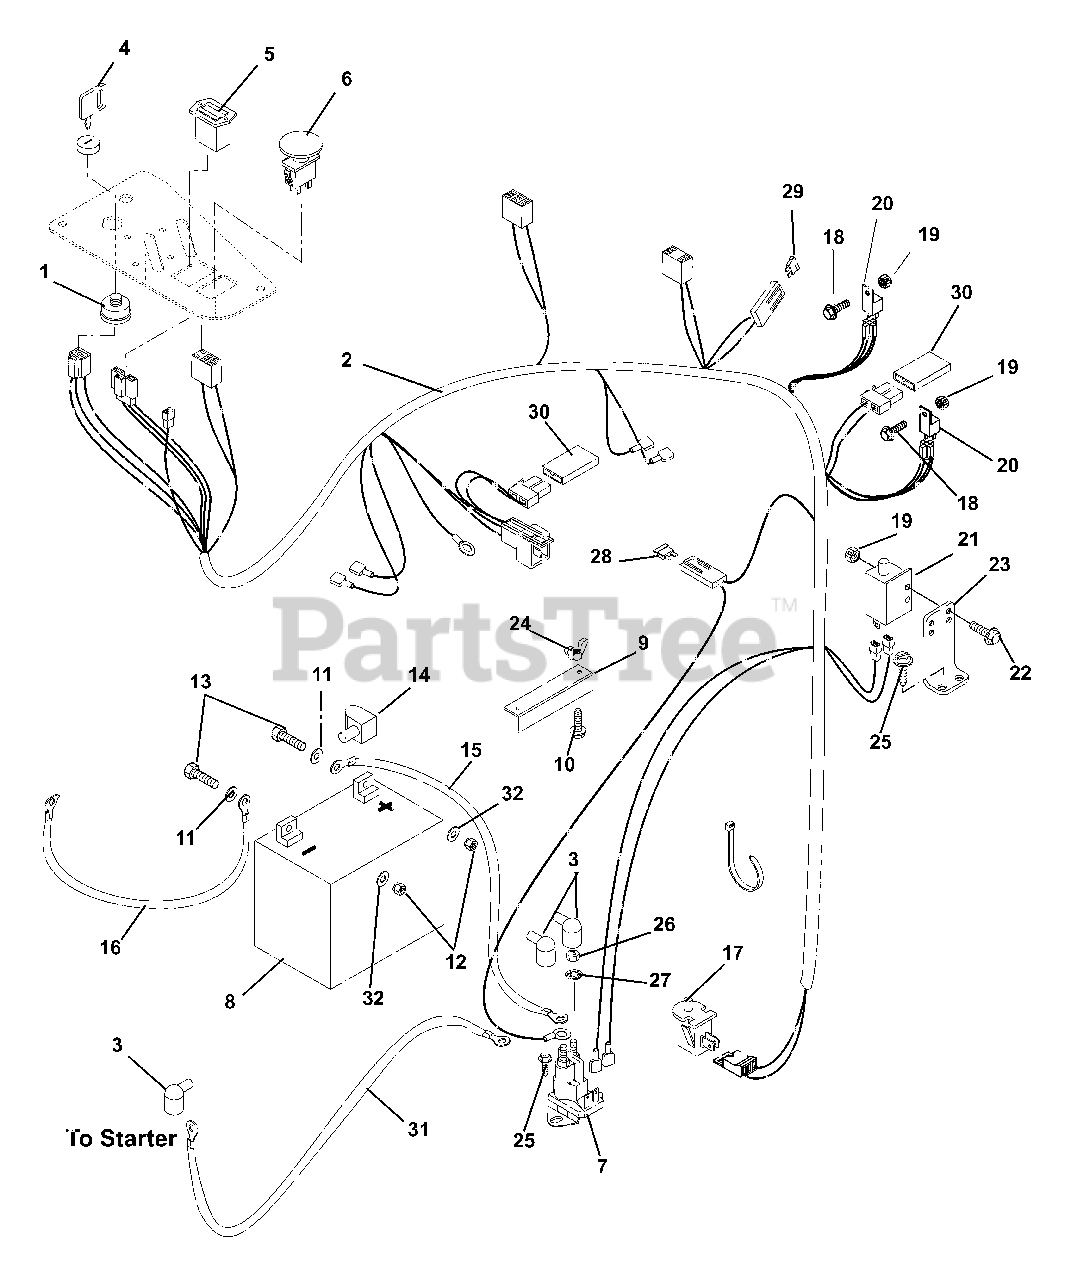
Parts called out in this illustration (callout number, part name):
1	SWITCH, IGNITION
2	HARNESS,CZ-EYEQ REMOTE SOL.
3	BOOT, EYELET TERMINAL
4	KEY, W/ SHIELD
5	HOURMETER-QUARTZ 80VDCMAX
6	SWITCH, CLUTCH
7	SOLENOID
8	BATTERY, 300 CCA 10U1L
9	HOLD DOWN
10	BLT-RDHDSQNK .25-20X7.50 GR2YZ
11	@WSHR-FL-STL.281X.62X.065 YWZC
12	@NUT-HEX .25-20 YWZC
13	@BLT-HEX .25-20X.75 GR5 YWZC
14	INSULATOR
15	CABLE, POS. BAT. 9.00"
16	CABLE, NEGATIVE BATTERY 24.00
17	SWITCH- SNAP MTG N.O.
18	@SCR-MCH 10-24X.50 HWH YWZC
19	@NUT-LK-NYL 10-24 W/INSRT YWZC
20	RELAY,SEALED W/DIODE
21	SWITCH- SINGLE POLE N.O.
22	@SCR-MCH 10-24X.75 HWH YWZC
23	BRAKE SWITCH MOUNT - BLACK
24	NUT-LK WING .250-20 YWZC
25	@SCR-TAP .25-20X.50 HWH TR YWZ
26	NUT-JAM .31-24 YWZC
27	@WSHR-LK .31X.078 REG YWZC
28	FUSE-25 AMP ATC TYPE
29	FUSE 20AMP
30	DIODE, CONNECTOR SHELL
31	CABLE, STARTER .31X23.00X.31
32	@WSHR-LK .25X.062 REG YWZC
